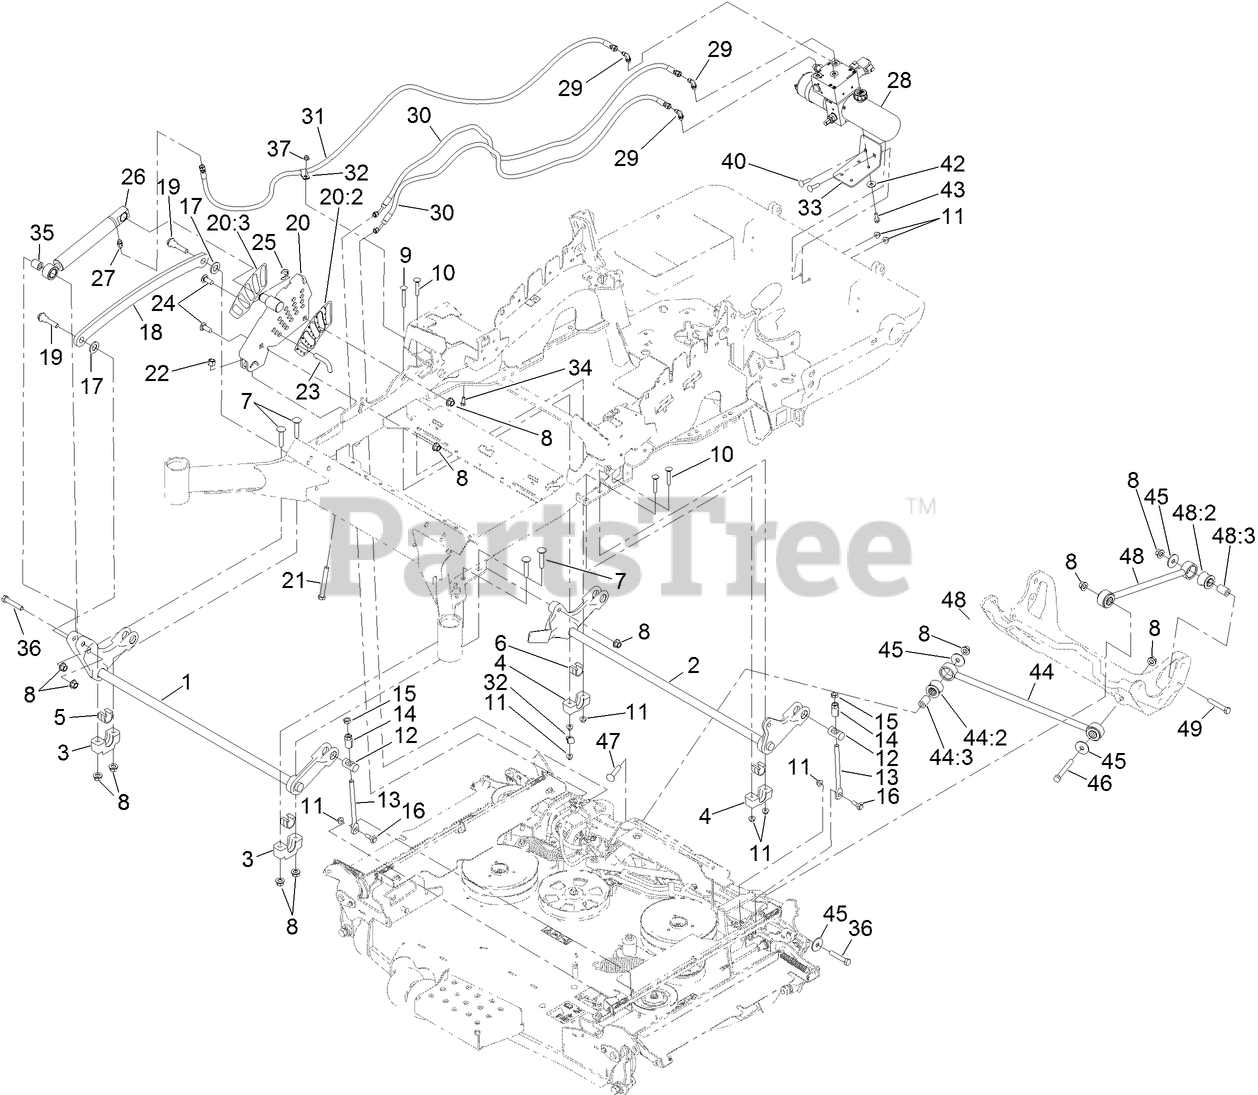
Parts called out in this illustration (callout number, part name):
1	DECKLIFT-FRONT
2	LIFT-DECK, REAR
3	SUPPORT-CROSS SHAFT, BEARING
4	SUPPORT-CROSS SHAFT, BEARING REAR
5	BEARING-CROSS SHAFT, FRONT
6	BEARING-CROSS SHAFT, REAR
7	BOLT-CARR
8	NUT-LOCK
9	SCREW-CARR
10	SCREW-CARR
11	NUT-HF, NI
12	TRUNNION
13	LINK-ADJUSTER, DECK LIFT
14	ADJUSTER-LIFT, DECK
15	NUT-JAM
16	SCREW-SHOULDER, HHF
17	WASHER-FLAT
18	LINK-LIFT, DECK
19	SCREW-HHF, SHOULDER
20	HOC ASM
20:2	DECAL-HEIGHT OF CUT
20:3	DECAL-HEIGHT OF CUT, OUTER
21	BOLT-TAP
22	NUT-LOCK, NI
23	PIN-HOC
24	SCREW-CARR, SHORT NECK
25	RING-RETAINING
26	CYLINDER-LIFT
27	Adapter, Straight
28	POWER UNIT
29	Adapter, 90?
30	HOSE-HYD, HP
31	HOSE-HYD, HP
32	R-CLAMP
33	MOUNT-POWER UNIT
34	SCREW-HH
35	SPACER-PIVOT
36	SCREW-HH
37	NUT-HF, NI
40	SCREW-CARR
42	WASHER-SPRING
43	SCREW-HHF
44	PANHARD ROD ASM
44:2	BUSHING-SUSPENSION, RUBBER
44:3	SPACER
45	WASHER-THRUST
46	SCREW-HH
47	SCREW-CARR
48	DECK STRUT ASM
48:2	BUSHING-SUSPENSION, RUBBER
48:3	SPACER
49	SCREW-HH
